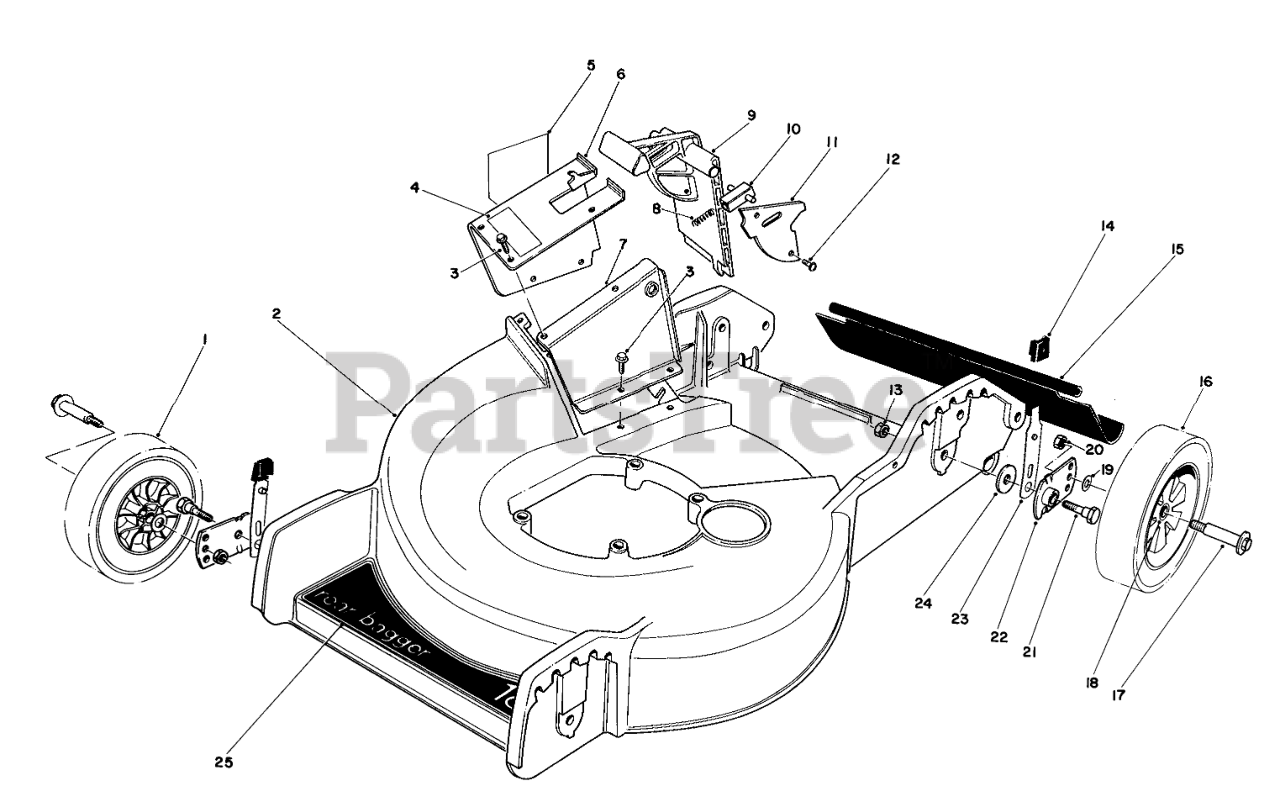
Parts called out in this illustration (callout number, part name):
1	Wheel & Tire Assembly (Incl. Ref. #18)
2	Housing
3	SCREW
4	Decal-Door
5	DECAL-DANGER
6	Tunnel-Outer (Incl. Ref. #4 & 5)
7	Inner Tunnel
8	SPRING-COMPRESSION, LATCH
9	Door Mulching
10	Door Latch
11	Cover Door
13	NUT-LOCK, NI
14	KNOB-ARM
15	SHIELD - TRAILING
16	Wheel & Tire Assembly (Incl . Ref. #18)
17	BOLT-WHEEL
18	BUSHING
19	WASHER
20	Nut
21	PIVOT SCREW
22	PIVOT ARM ASSY
23	SPRING ARM ASM
24	PIVOT WASHER
25	DECAL-DECK
